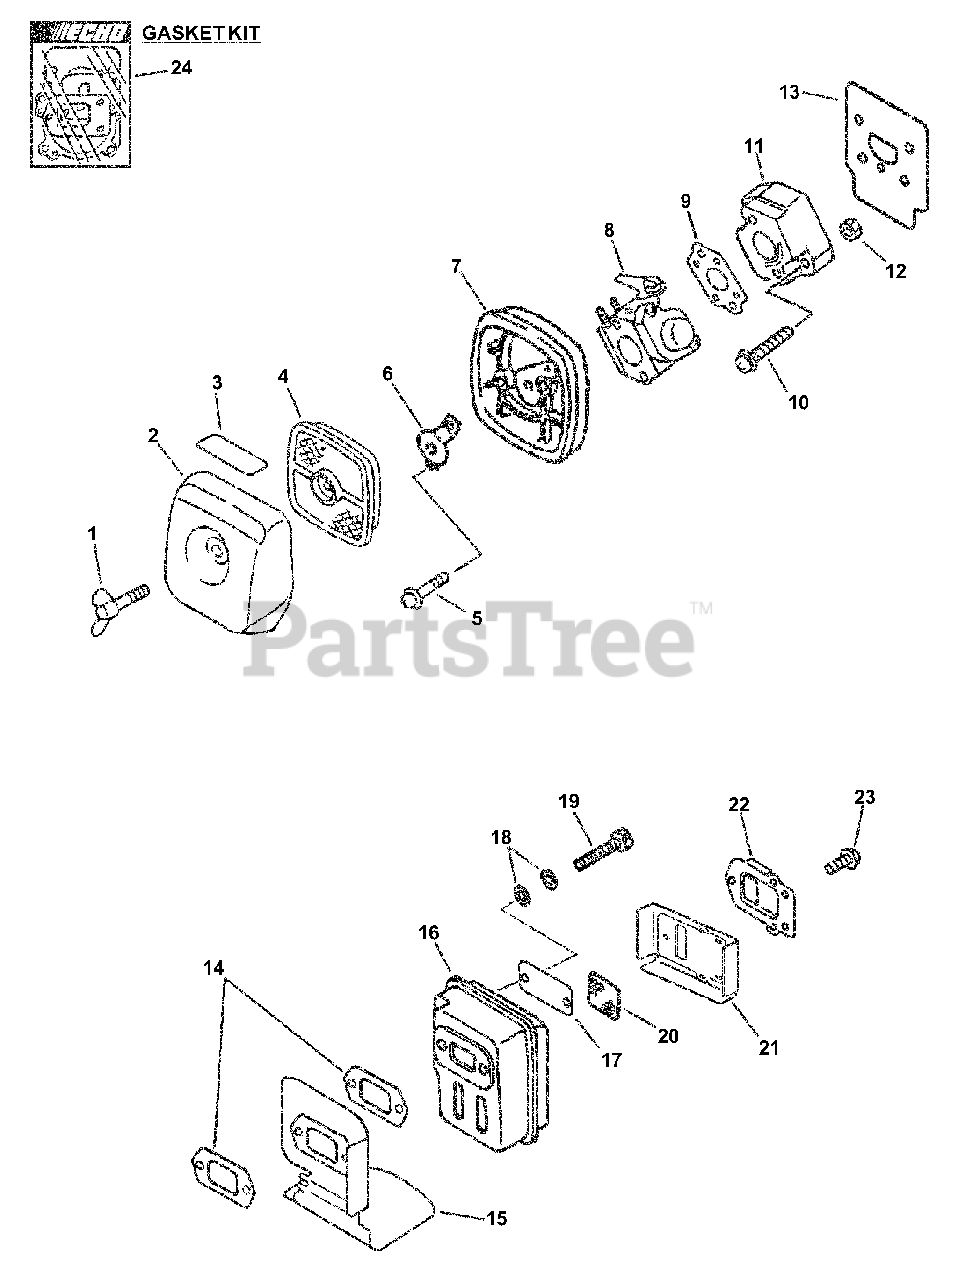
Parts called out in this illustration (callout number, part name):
1	THUMBSCREW
2	COVER, AIR FILTER - BLACK
3	LABEL - CHOKE
4	FILTER, AIR - SINGLE LAYER
5	SCREW - 5X65
6	PLATE, PREVENT
7	CASE, AIR FILTER
8	CARBURETOR C1U-K58
9	GASKET, INTAKE
10	SCREW - 5X20
11	INSULATOR, INTAKE
13	SHIELD, INTAKE
14	GASKET, EXHAUST
15	SHIELD, EXHAUST
16	MUFFLER
18	WASHER - CONICAL
19	SCREW - 5X55
20	SCREEN, SPARK ARRESTOR
21	GASKET, EXHAUST
22	GUIDE, EXHAUST
23	SCREW - 4X10
24	GASKET KIT
